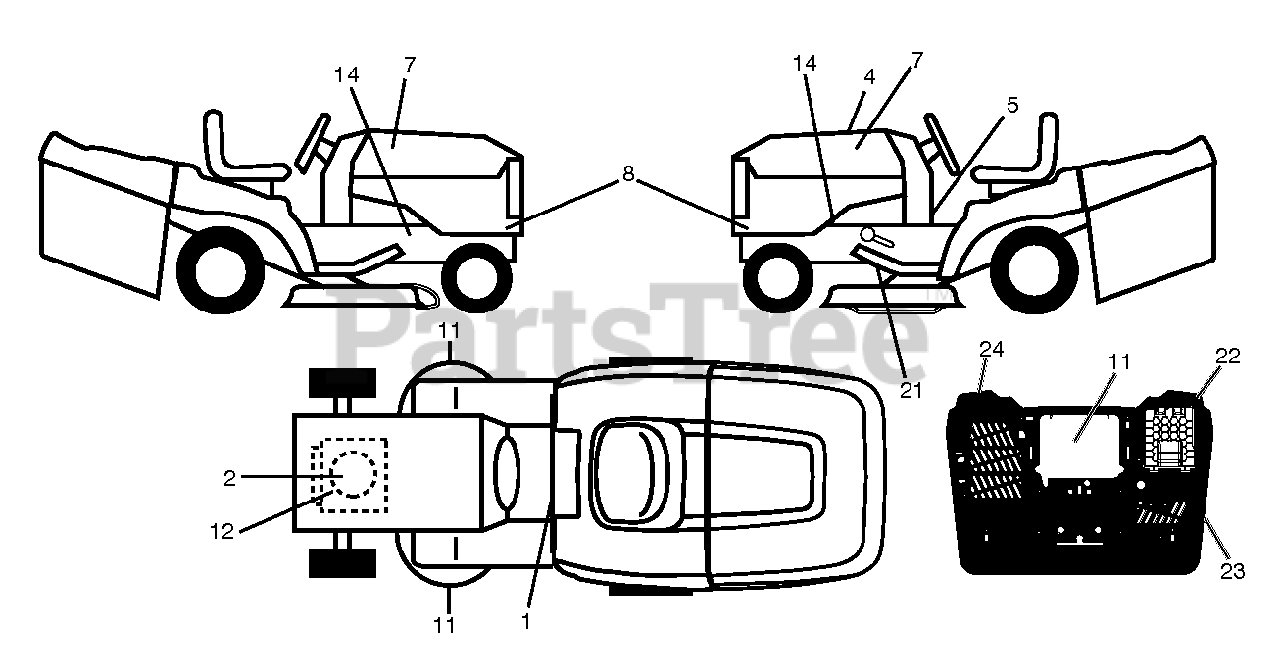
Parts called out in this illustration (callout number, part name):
1	DECAL.TRAC.FNDR.GLBLWRNG.RDYST
2	DECAL.ENGINE.WARNING
4	DECAL.RPL.BSM40.END.TCRD.97R.
5	Decal, Instruction MLCH/BG VERT
7	DECAL.BADGE.170MM.TEXTLOGO.
8	DECAL.SDPNL.HUSQGT.TC238.RH/LH
11	DECAL.CUTFINGER.CE.02
12	DECAL.ENG.BS.656CC.ENDUR.38227
14	DECAL.CHASSIS.HOT.MUFFLER
21	DECAL DECAL V-BELT 97 CM CRD
22	DECAL DECAL.TEX.CRD.BATTERY.DO
23	DECAL DECAL.BYPASS.BACKPLATESI
24	DECAL DECAL.WARNING.COMBINED.T
